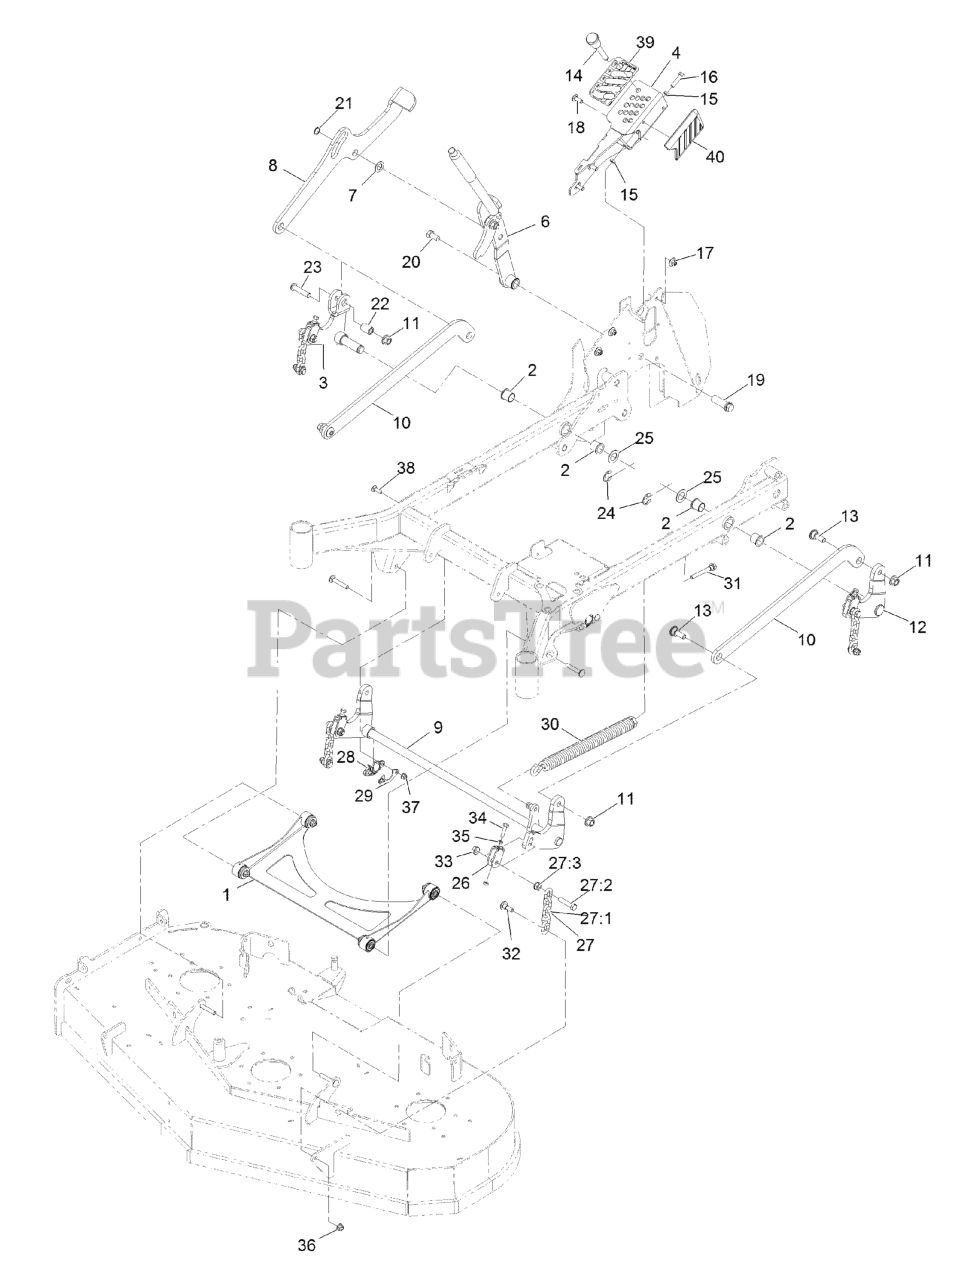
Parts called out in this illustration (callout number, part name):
1	ASM, Deck Strut
2	BUSHING, IGUS
3	Weld, Bellcrank, Rt
4	Weld, HOC Index
6	ASM, HOC Lever
7	WASHER-THRUST
8	Strap, HOC Index
9	Weld, HOC Cross Shaft
10	Strap, HOC Lift
11	Nut-Lock 1/2-13
12	Weld, Bellcrank
13	Bolt, Shoulder
14	PIN-HOC
15	NUT-JAM
16	BOLT-HH
17	Nut-Nyloc 3/8-16 Flg
18	SCREW-CARR
19	HUB-THREADED
20	SCREW-HH
21	RING-SNAP
22	Spacer, HOC
23	Screw-HSBH
24	RING-RETAINING, EXT
25	Washer-Flat
26	YOKE-ADJUST, DECK
27	DECK LIFT CHAIN ASM
27:1	CHAIN-LIFT, DECK
27:2	SCREW-HH
28	BUSHING-FLANGE
29	GUSSET-LIFT, DECK
30	SPRING-EXTENSION
31	BOLT-SHOULDER
32	SCREW-SHOULDER, HHF
34	SCREW-HH
35	NUT-JAM
36	NUT-HF, NI
37	NUT-HF, NI
38	BOLT-CARR
39	Decal-Height Of Cut
40	Pad, Knee
